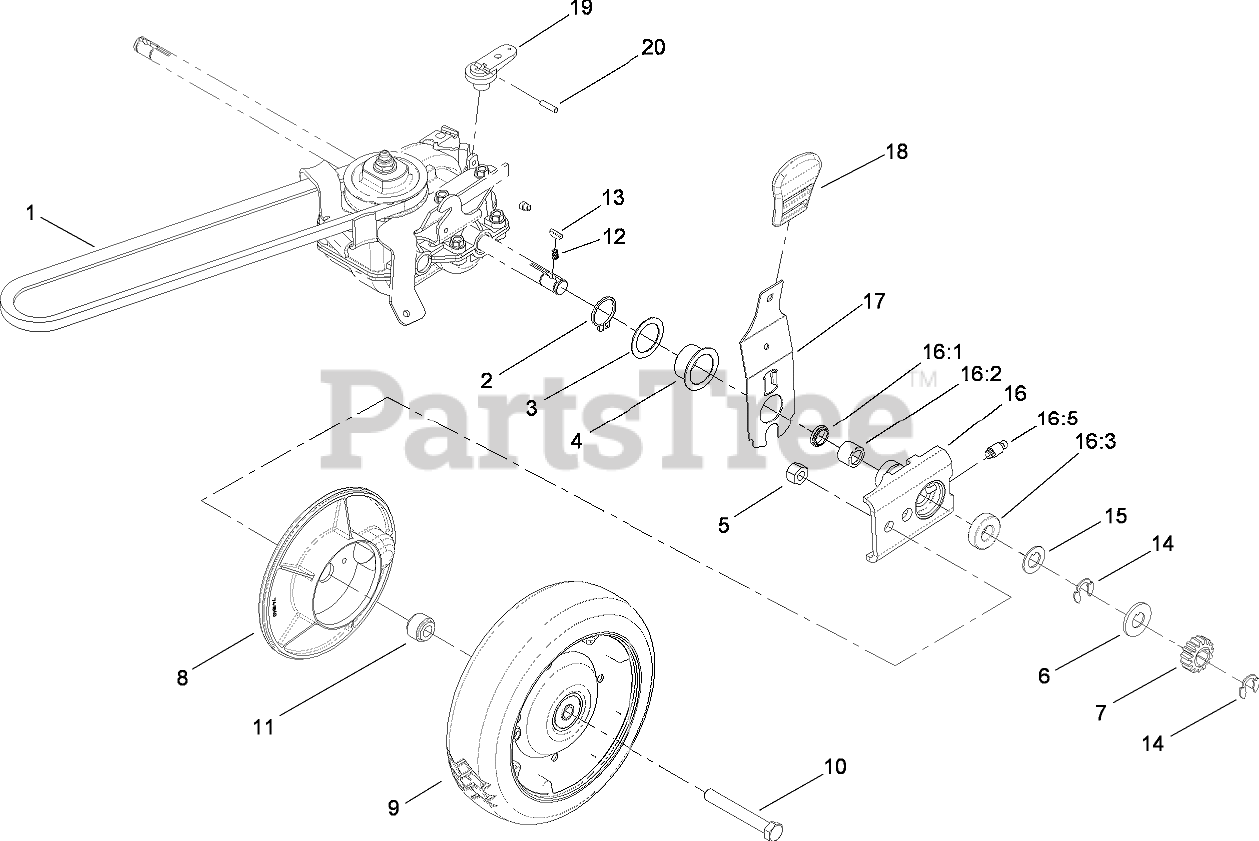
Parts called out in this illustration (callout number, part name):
1	V-BELT
2	RING-RETAINING
3	WASHER
4	BUSHING-FLANGE
5	NUT-LOCK, CONE
6	WASHER-THRUST, OUTER
7	GEAR-PINION
8	COVER-WHEEL
9	Wheel And Tire ASM
10	SCREW-HH
11	SPACER-COVER, WHEEL
12	SPRING-COMPRESSION
14	RING-RETAINING
15	WASHER-THRUST, OUTER
16	PIVOT ARM ASM
16:1	SEAL-OIL
16:2	BEARING-ROLLER
16:3	BEARING-WHEEL
17	REAR SPRING ARM ASM
18	KNOB-HOC
19	LEVER-SHIFT
20	PIN-COIL
